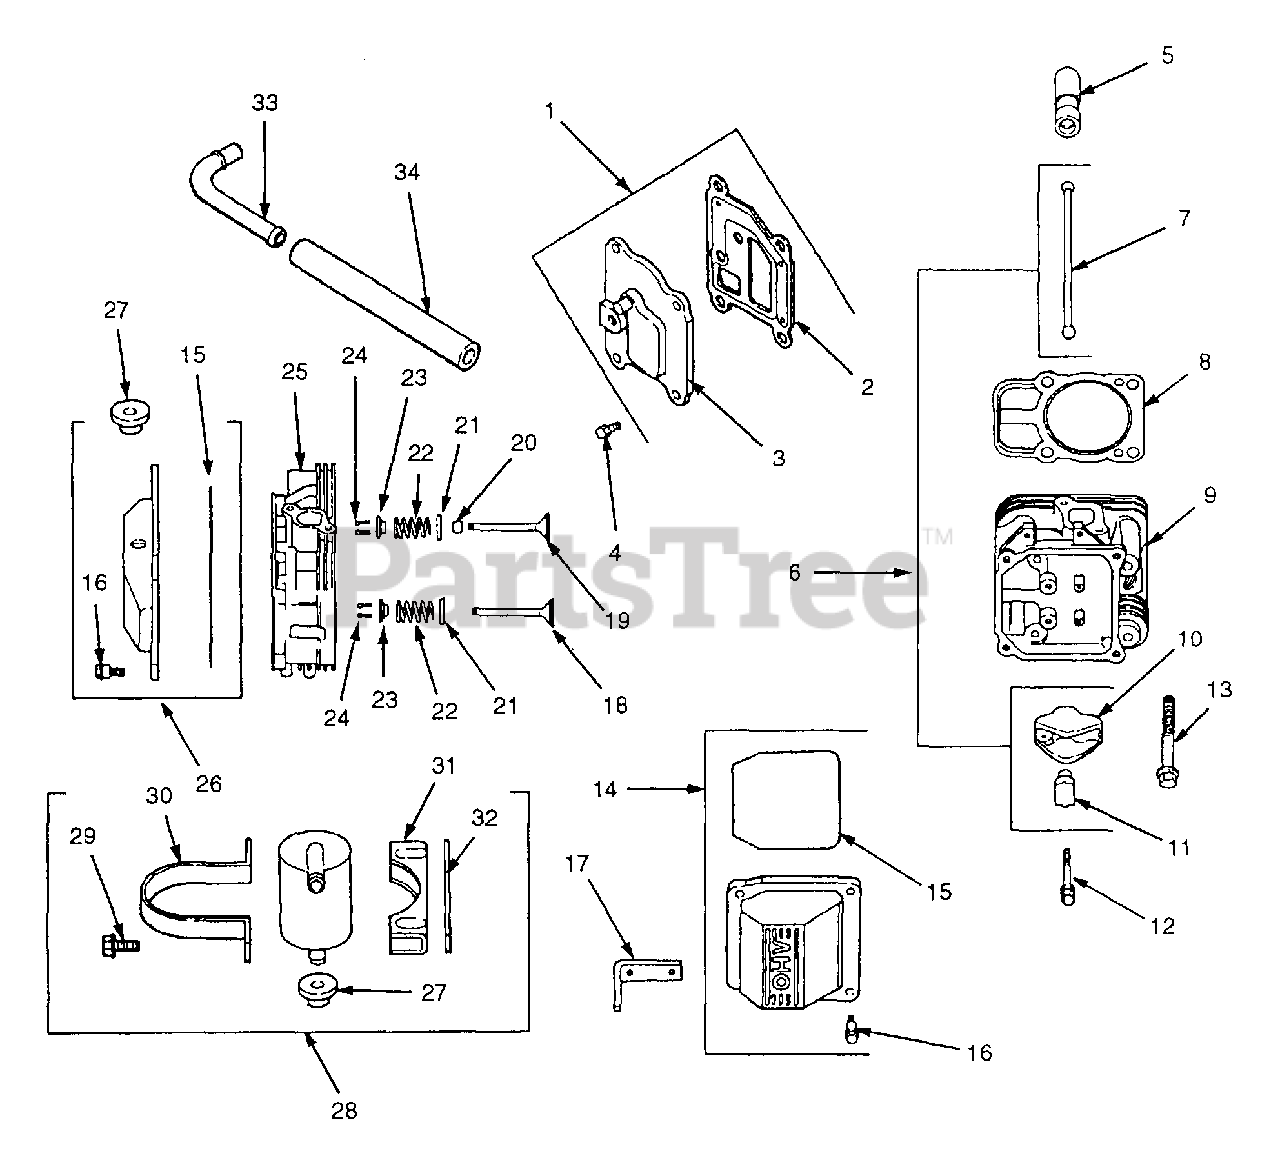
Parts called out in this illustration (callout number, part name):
1	Cover Kit, Breather w/Gasket
2	Gasket, Breather
3	Cover, Breather
4	Screw, Hex Flange, M6 x 1.0 x 20
5	Lifter, Valve
6	Kit, Valve Train
8	Gasket, Cylinder Head
9	Head Assembly, #2 Cylinder
11	Pivot, Rocker Arm
12	Screw, Hex Flange, M6 x 1.0 x 34
13	Screw, Hex Flange, M10 x 1.5 x 90
14	Kit, Valve Cover
15	O-Ring
16	Screw, Shoulder
17	Strap, Lifting
18	Valve, Exhaust, Std.
19	Valve, Intake, Std.
20	Seal, Valve Stem
21	Retainer, Spring
22	Spring, Valve
23	Cap, Valve Spring
24	Kit, Retainer
25	Head Assembly, #1 Cylinder
26	Kit, Valve Cover - Breather
27	Grommet, Rubber
28	Kit, Breather Separator
29	Screw, Hex Flange, M5 x 0.8 x 16
30	Strap, Breather
31	Bracket, Breather Separator
34	Hose, Flexible
